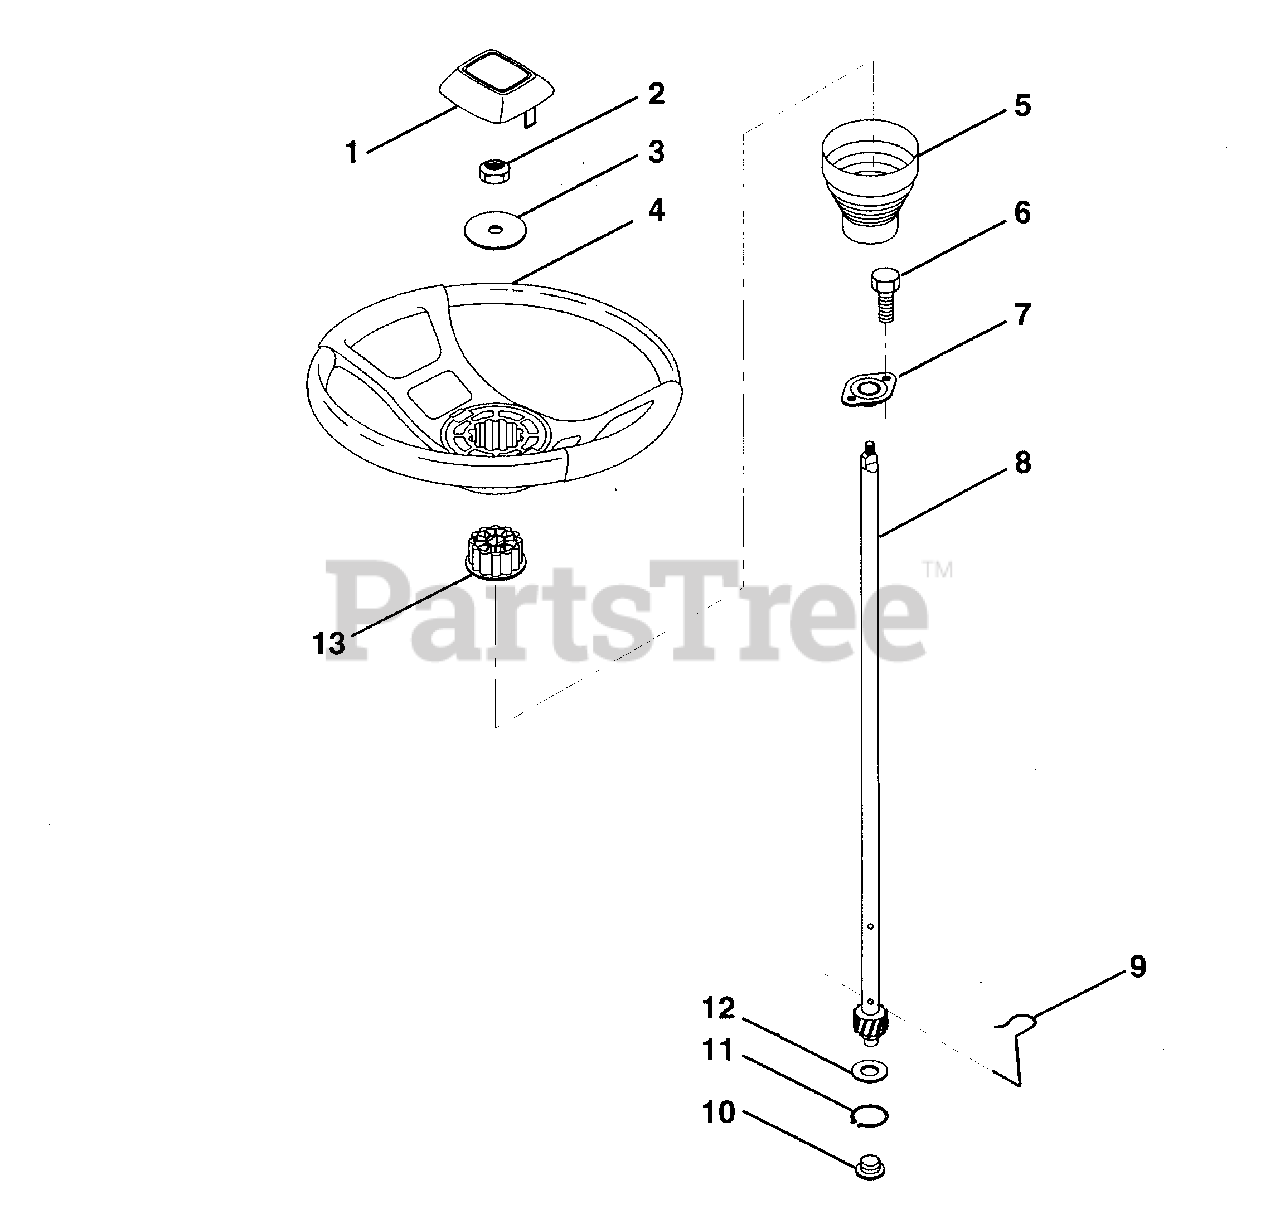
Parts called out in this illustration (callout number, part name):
1	Insert, Steering Wheel
2	Locknut 3/8-24 UNF
3	Washer 12/32 x 2-3/8 x 8 Gauge
4	Steering Wheel
5	Sleeve, Steering
6	Screw, Hex #10-16 x 1/2 TY-B
7	Bushing, Steering
8	Shaft, Steering
9	Clip, Steering
10	Bushing, Lower, Steering
11	Ring, Retaining
12	Washer 21/32 x 1 x 16 Gauge
13	Adaptor, Steering Wheel
